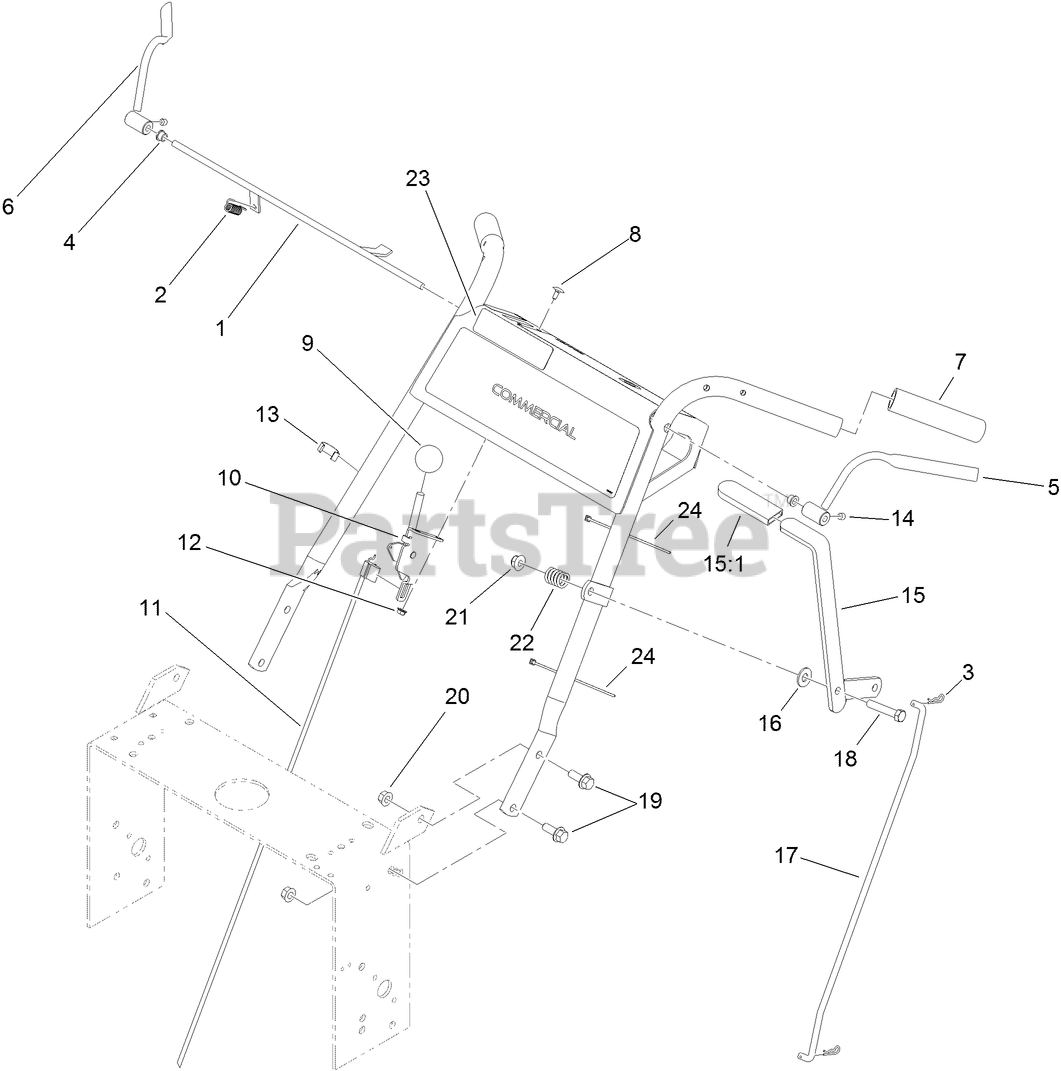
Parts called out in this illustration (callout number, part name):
1	ROD-CONTROL, OPERATOR PRESENCE
2	SPRING-EXTENSION
3	PIN-COTTER
4	BUSHING-NYLON
5	LH OPERATOR PRESENCE CONTROL LEVER ASM
6	RH OPERATOR PRESENCE CONTROL LEVER ASM
7	GRIP-FOAM
8	BOLT-CARR
9	KNOB-BALL
10	LEVER-CONTROL
11	CABLE-CONTROL, THROTTLE
12	NUT-LOCK, FLANGE
13	Clip-Cable
14	SCREW-SET
15	LEVER ASM
15:1	GRIP-LEVER
16	WASHER-FLAT
17	Linkage-Blade, Upper
18	SCREW-HH
19	NUT-HF
20	SCREW-HHF
21	NUT-HF, NI
22	SPRING-COMPRESSION
23	DECAL-ARRESTER, SPARK
24	TIE-CABLE
